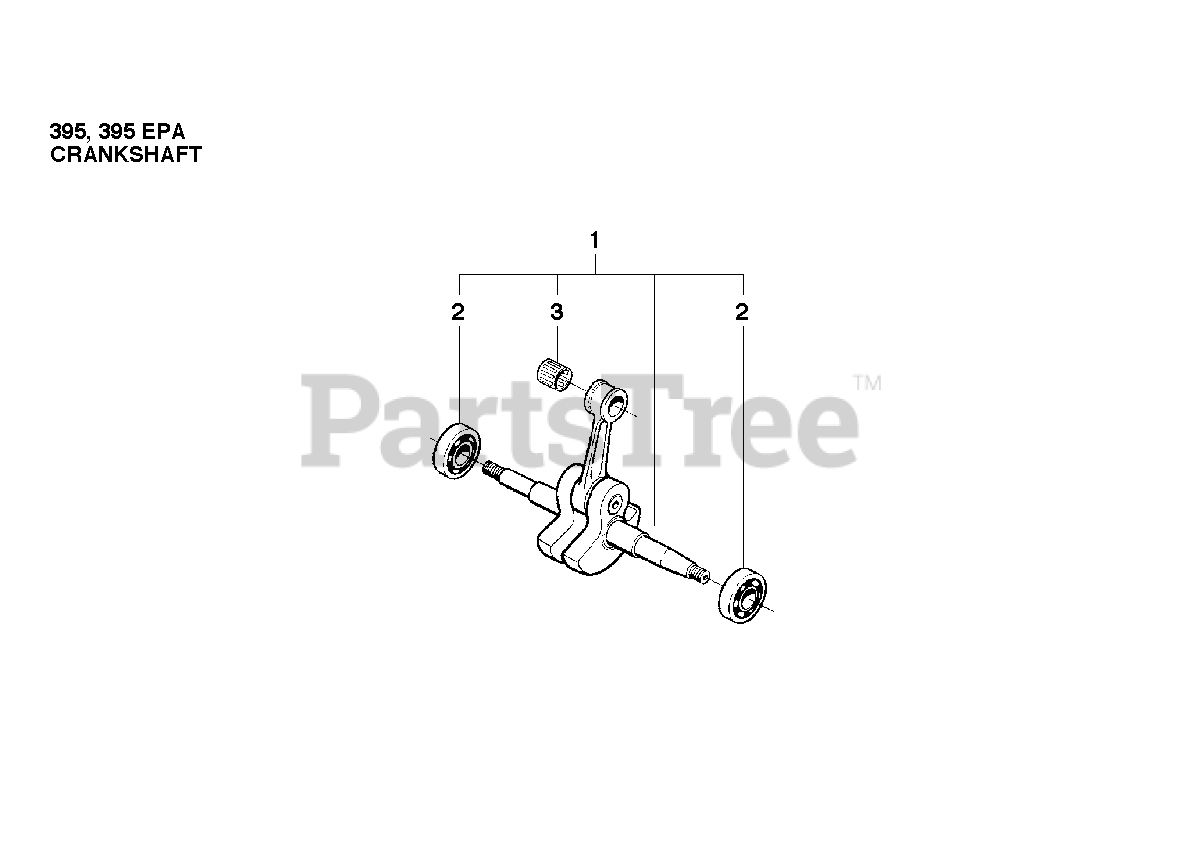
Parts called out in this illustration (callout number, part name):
1	CRANKSHAFT
2	BALL BEARING 6203 C3
3	SUPPORT BUSHING
